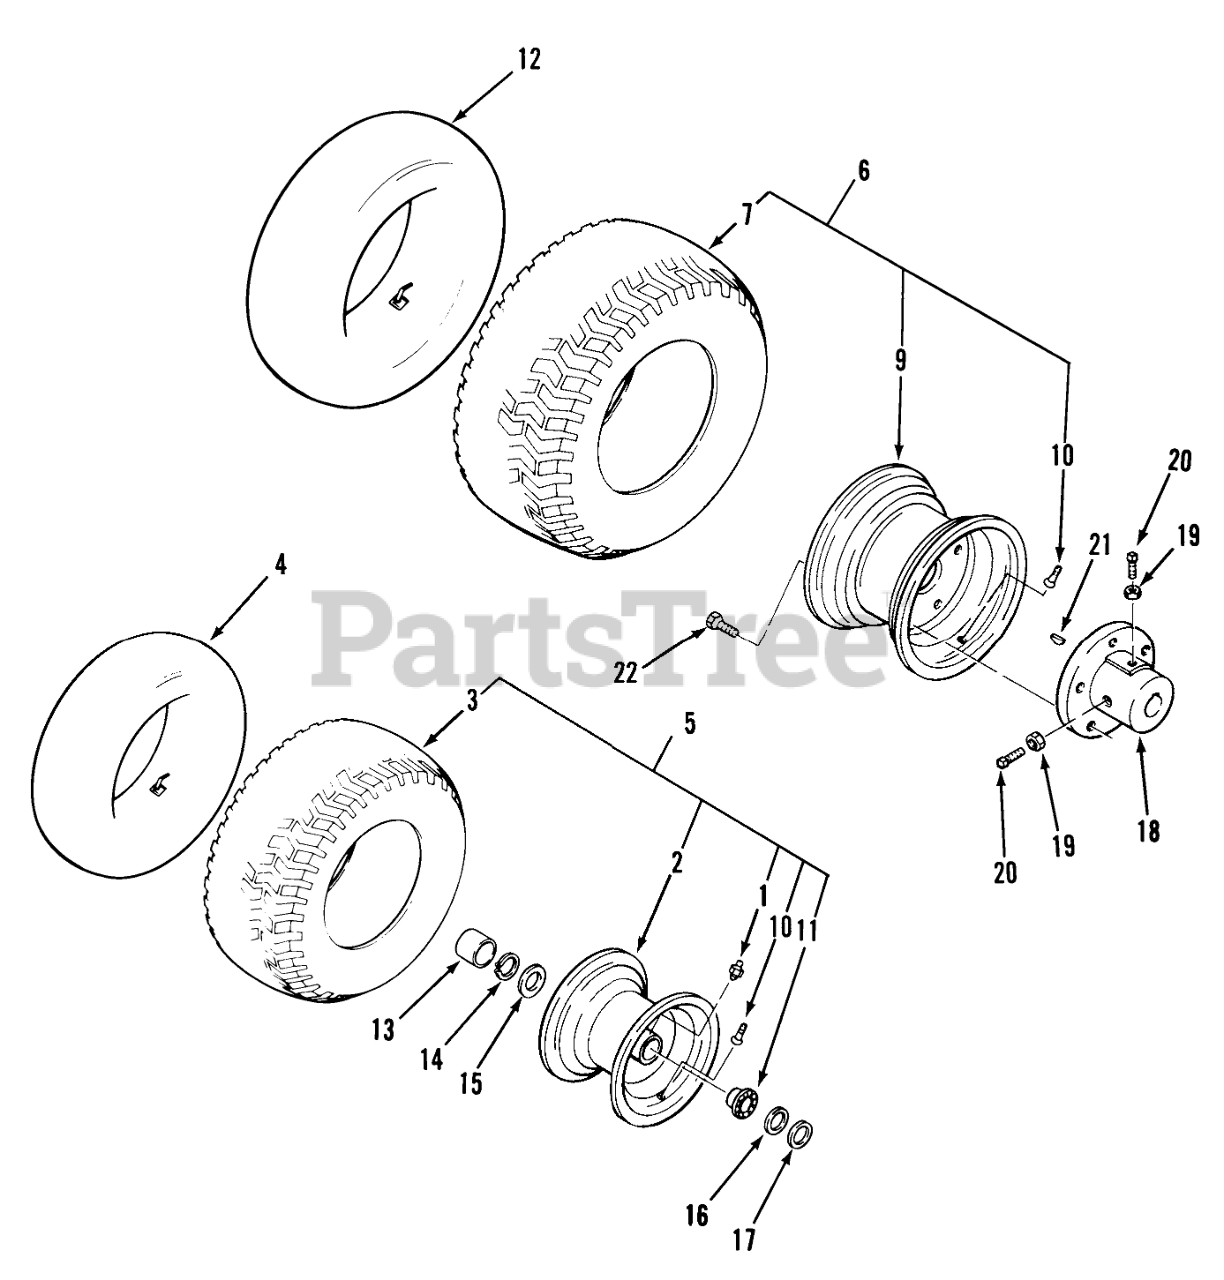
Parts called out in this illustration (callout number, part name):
1	Zerk
2	WHEEL ASSY
3	TIRE TURF SAVER 16X6.50-8
4	TUBE-INNER
5	ASSY-WHEEL & TIRE
6	Tire & Wheel Assy
7	TIRE 22 X 7.50-12
9	Wheel
10	VALVE
11	Ball Bearing
12	INNER TUBE
13	HUB CAP-FLAT BLACK
14	Snap Ring
15	WASHER-WHEEL
16	WASHER
17	WASHER-SHIM
18	Hub-Rear
19	Nut
20	Screw-Set
21	WOODRUFF KEY
22	Lug Nut
